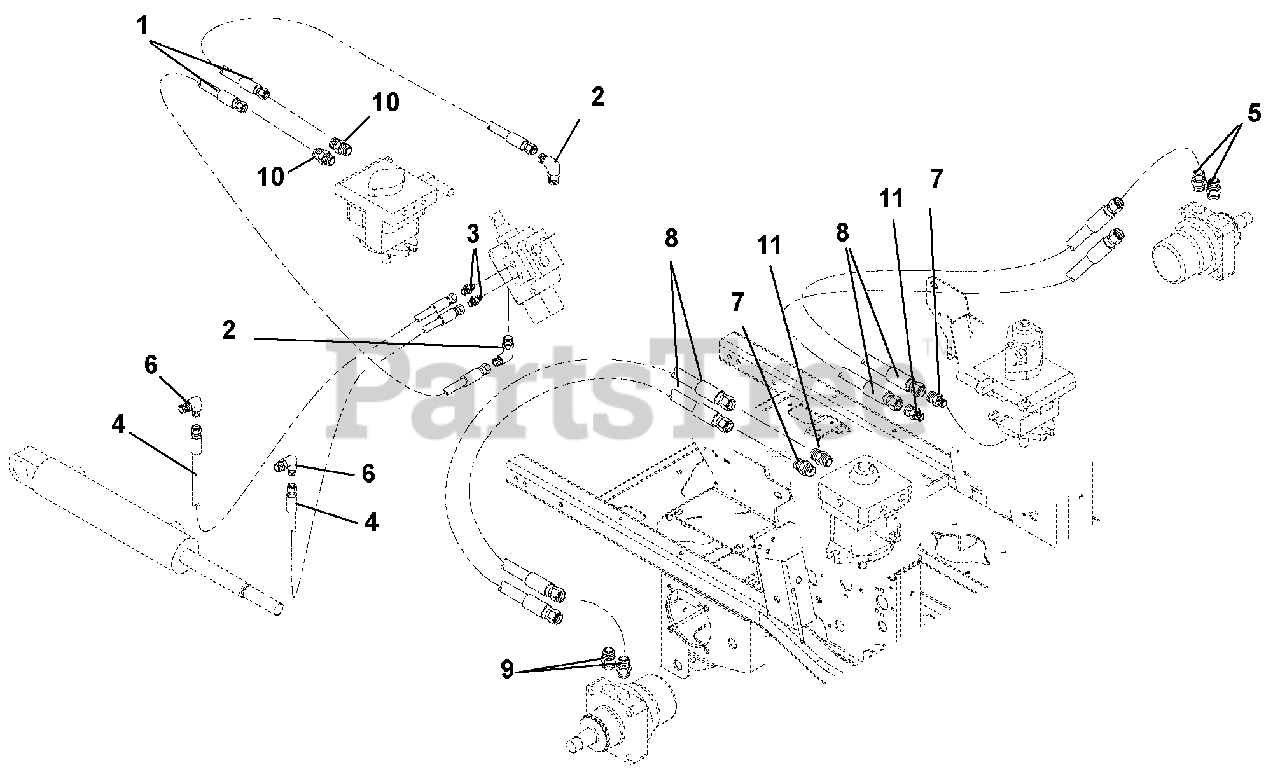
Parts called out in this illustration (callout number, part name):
1	Hose, Hydraulic
2	Hydraulic, Fitting Elbow
3	Adapter (4-6F5OLO)
4	Hose, Hydraulic
5	Fitting, Hydraulic Straight (8-10 F5OLO-S)
6	Fitting, Hydraulic (4 C5OLO)
7	Adapter, Face Seal 8 x 8 .50 O-Ring
8	Hose, Hydraulic .50
9	Adapter, Hydraulic Steel (M10 O-M8F)
10	Fitting, Hydraulic (4 F5OLO) (Supplied with pump)
11	Fitting,Hydraulic 45 Degree M8F-M80
